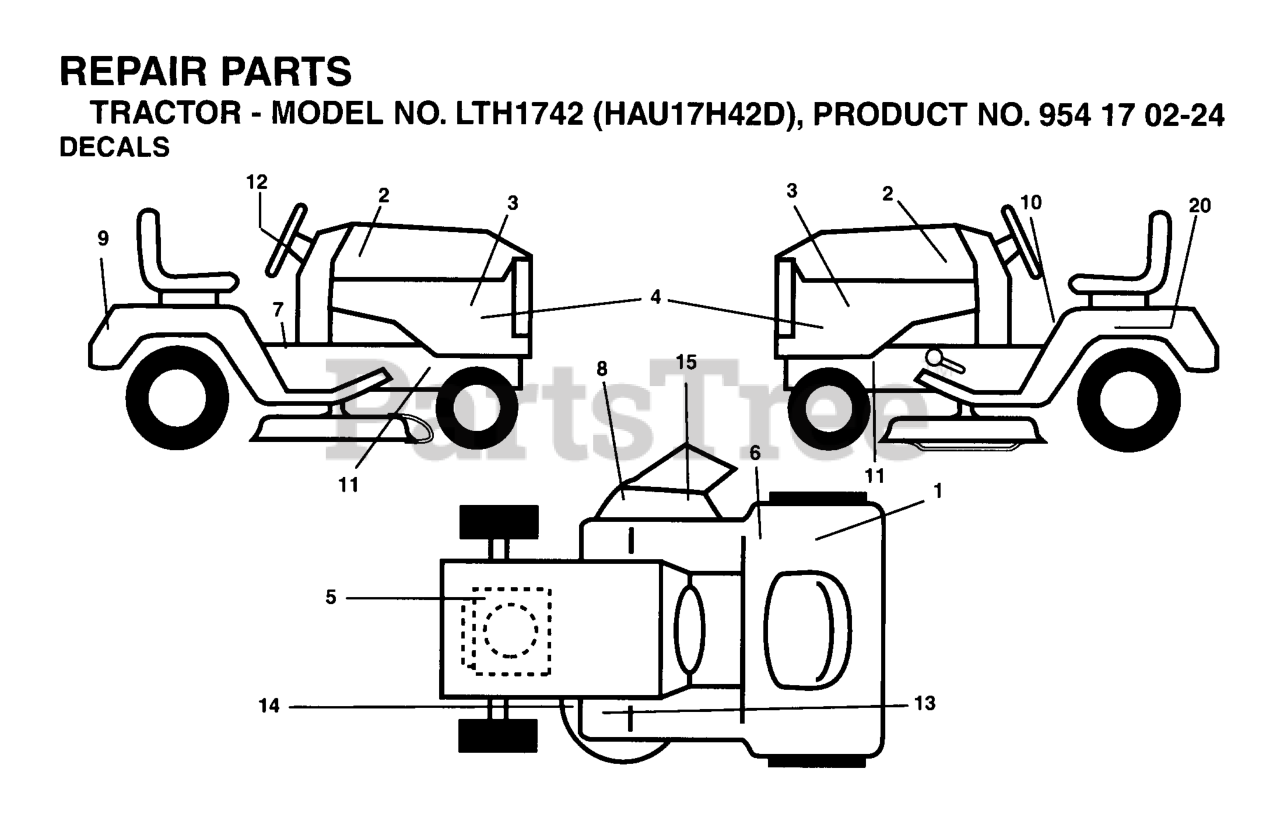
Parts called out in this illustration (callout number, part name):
1	DECAL
3	DECAL.HOOD.HUSQVARNA.INTERNATI
5	DECAL
6	DECAL 80 DBA
7	DECAL PARK BRAKE
8	DECAL.INTERNATIONL.CUTFINGER
10	LABEL
12	DECAL.STEERING.HUSQ.BLUE
13	DECAL
14	DECAL V BELT SCHEMATIC
15	DECAL, DEFLECT WARNING
20	DECAL BTRY SYMBOLS
